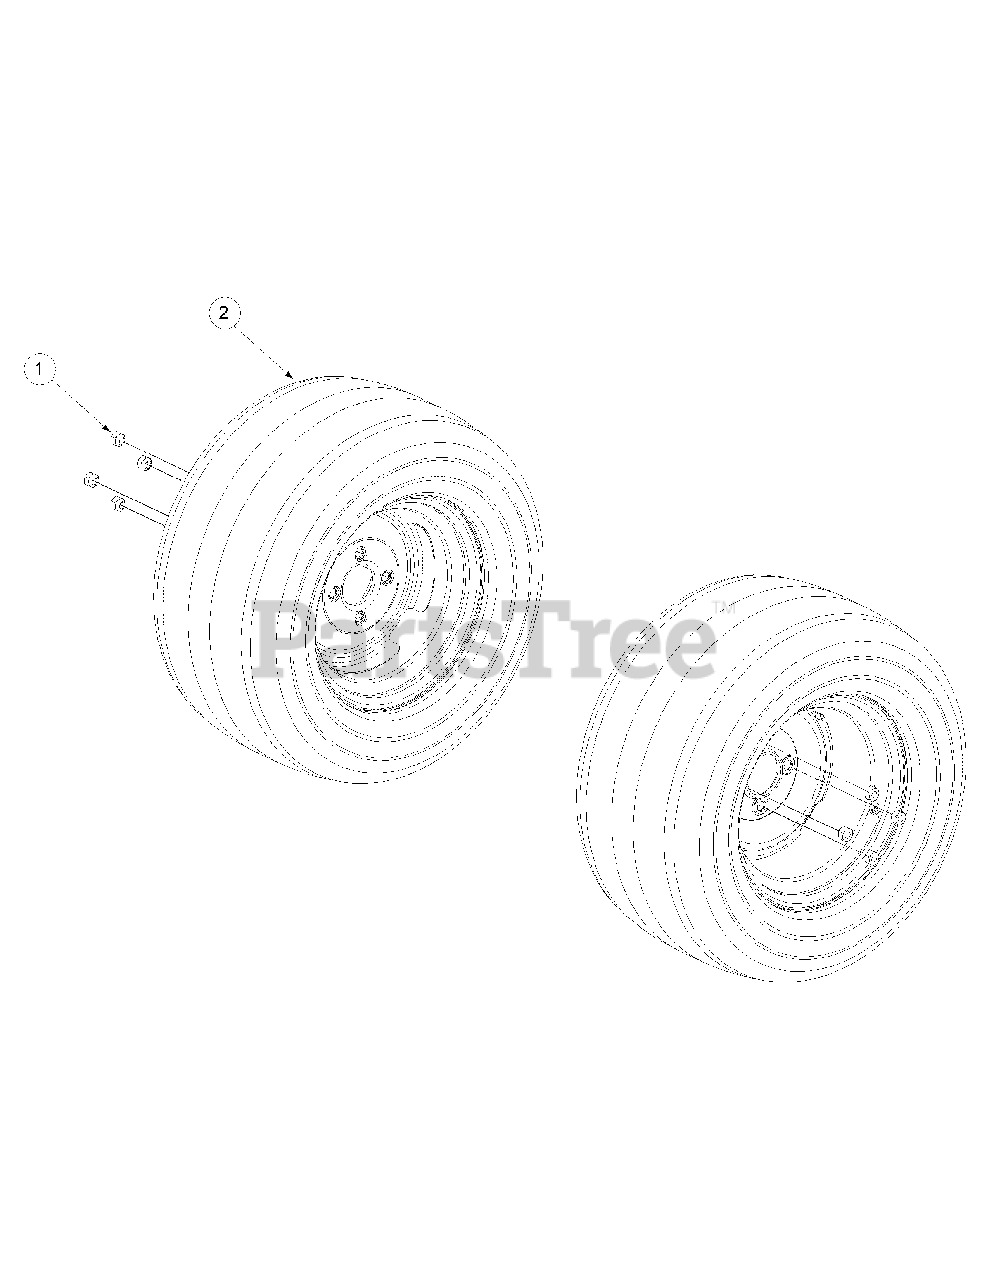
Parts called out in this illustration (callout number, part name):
1	Lug Nut, 1/2-20
2	Wheel Assembly, 23 x9.5-12, Turf Master Includes:
2	Tire, 23 x 9.50-12, Turf Master Rim, 12 Dia x 7.00 width
